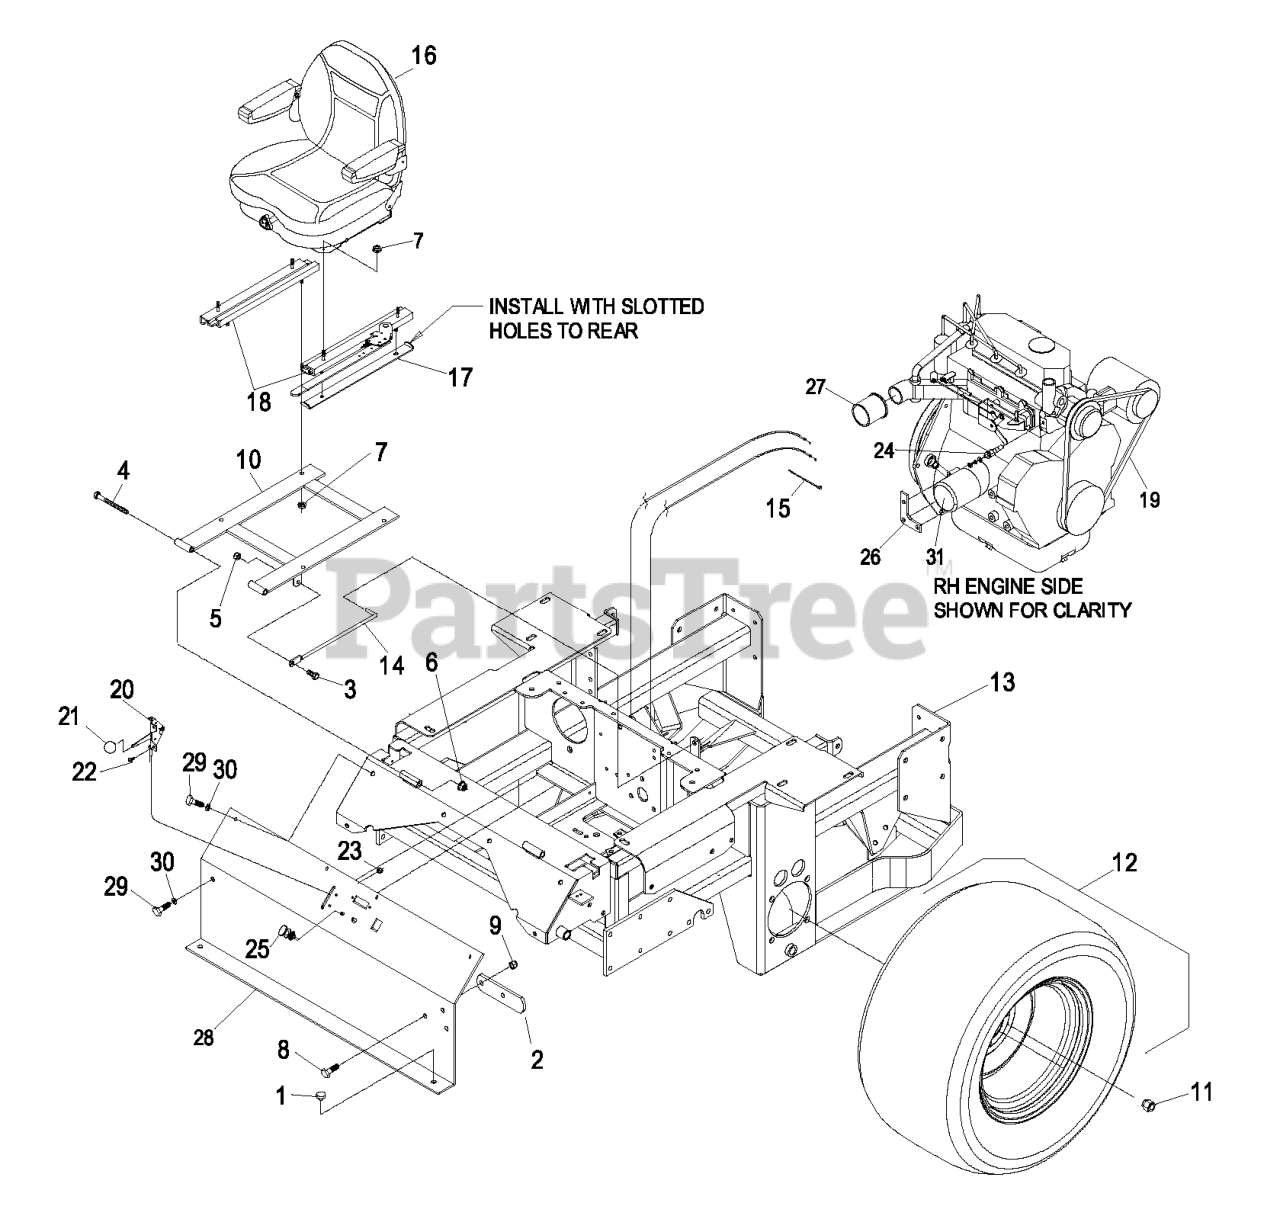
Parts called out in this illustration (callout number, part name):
2	STOP-BRAKE, PARK
3	SCREW-HH
4	SCREW-HH
5	NUT-LOCK, NI
6	NUT-LOCK, NI
8	SCREW-HH
9	NUT-HHF, WHIZ
11	NUT-LUG
13	ASM,ENGINE DECK W/DECAL
14	ROD,HOLDUP SEAT
15	TIE-PLASTIC
17	STOP-SEAT
18	TRACK-SEAT
19	Briggs & Stratton P/N 820271 Engine V-Belt
20	CABLE-THROTTLE
21	KNOB-BALL
22	BOLT-CARR
23	NUT-LOCK, NI
24	SENDER-TEMPERATURE
25	CABLE,CHOKE
27	BUSHING,1.75/2.00 RUBBER
29	SCREW-HH
30	WASHER-PLAIN
31	Briggs & Stratton P/N 820314 Oil Filter
